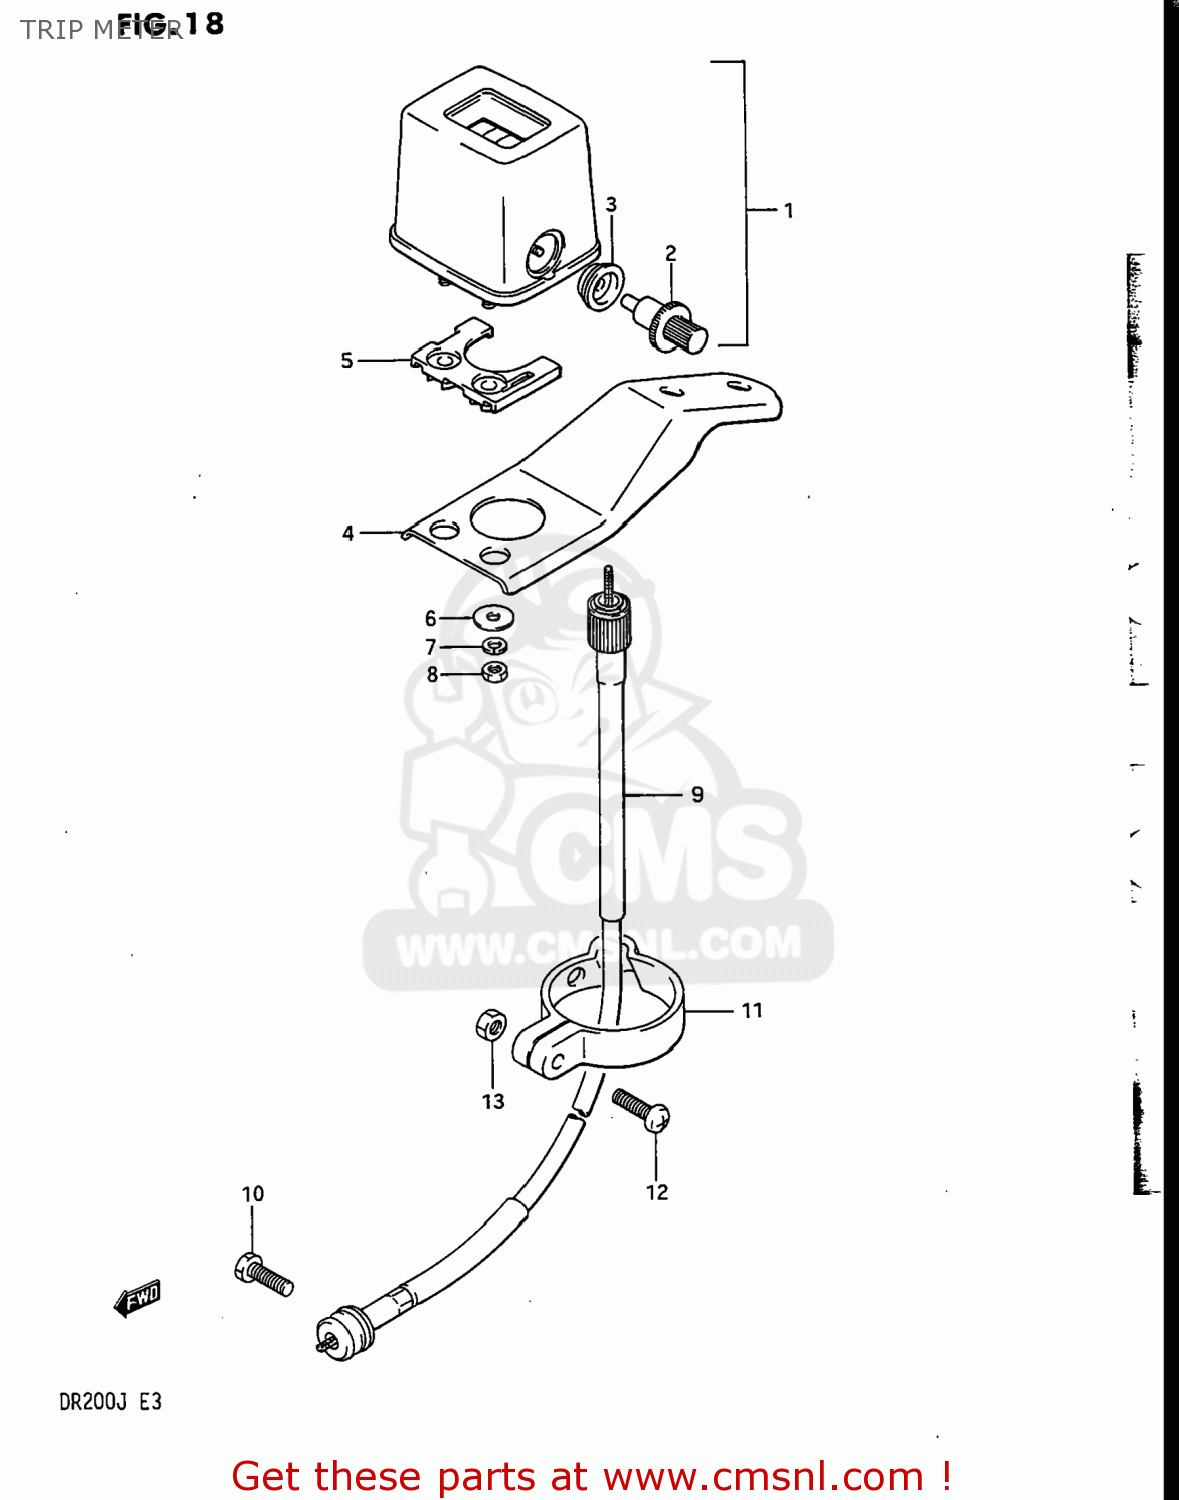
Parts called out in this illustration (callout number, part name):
1	TRIP METER
2	KNOB,TRIP METER
3	COVER,TRIPMETER KNOB
4	BRACKET,TRIPMETER
5	CUSHION,TRIPMETER
6	WASHER,METER
7	LOCK WASHER
8	NUT
9	CABLE ASSEMBLY,SPEEDOMETER
10	BOLT
11	CLAMP,SPEEDOMETER CABLE
12	SCREW
13	NUT ,5MM
